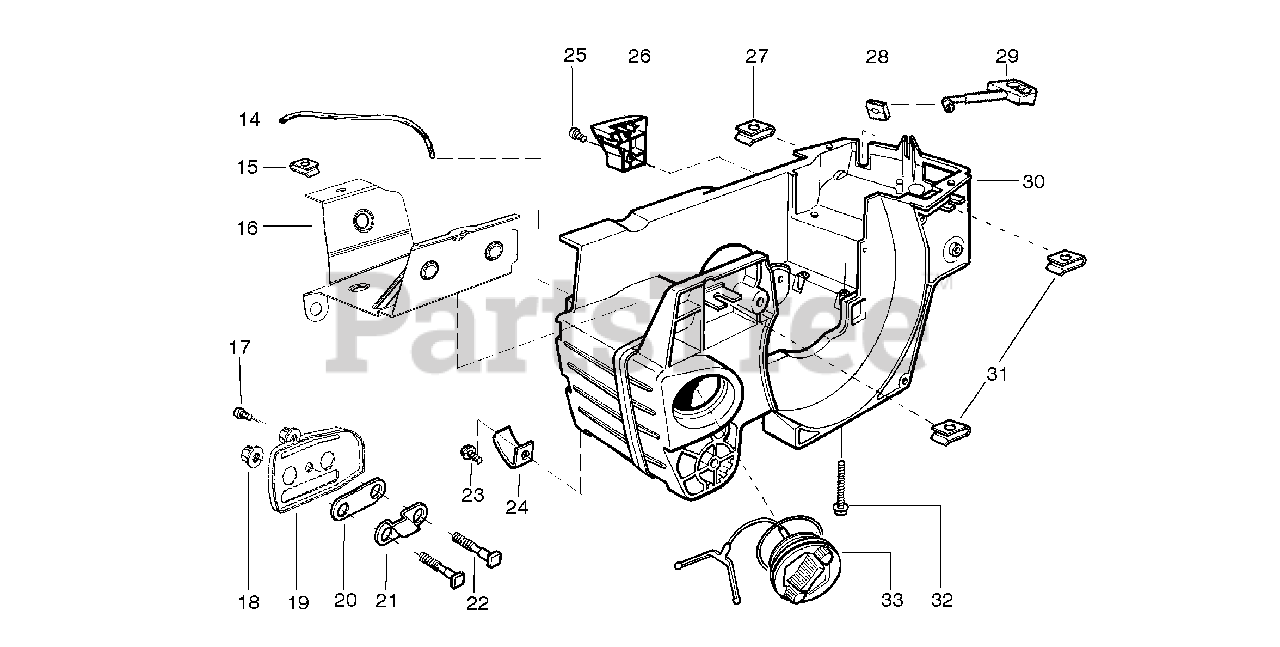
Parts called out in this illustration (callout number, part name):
14	Tube-Oil Vent
15	Clip-Retainer
16	Shield-Heat
17	Screw
21	Plate-Bar Stud
24	Chain Catcher
27	Nut-Type "U" Speed
29	Lever-Choke
30	Kit - Chassis Ass'y.
31	Nut-Type "U" Speed
33	Assy.- Oil Tank Cap
